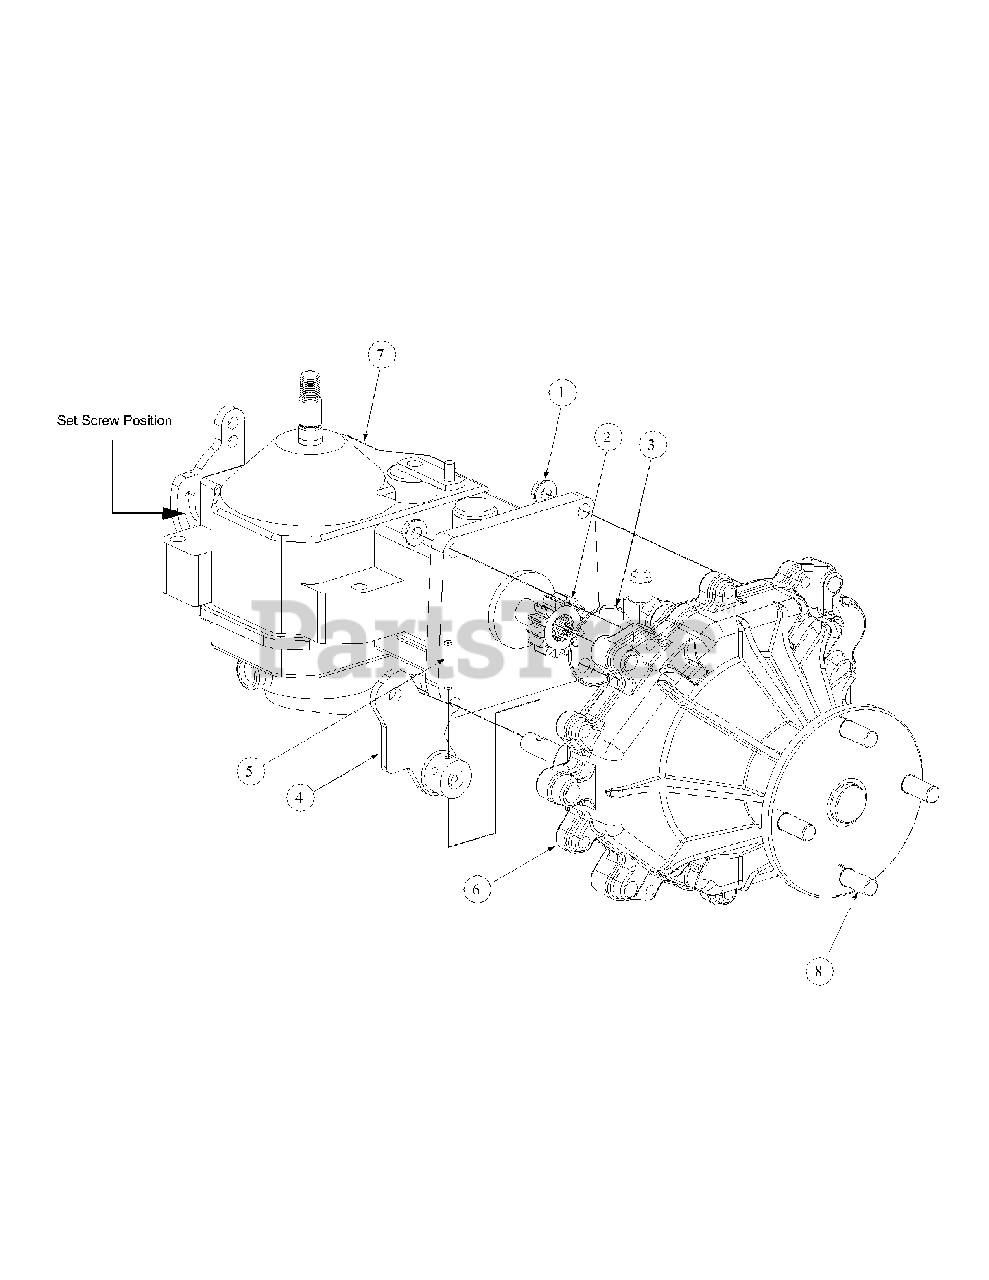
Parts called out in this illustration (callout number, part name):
1	Hex Flange, Lock Nut, 5/16-18
2	Gear, Spur, 14T
3	O-Ring, 2.00 x .070
4	Parking Brake Lever
5	Pin, Spirol, 3/16 x 1.25 HD
6	Transmission Assembly
8	Rib Neck Stud, 1/2-20
9	Set Screw, 5/16 - 24 x 1.25
